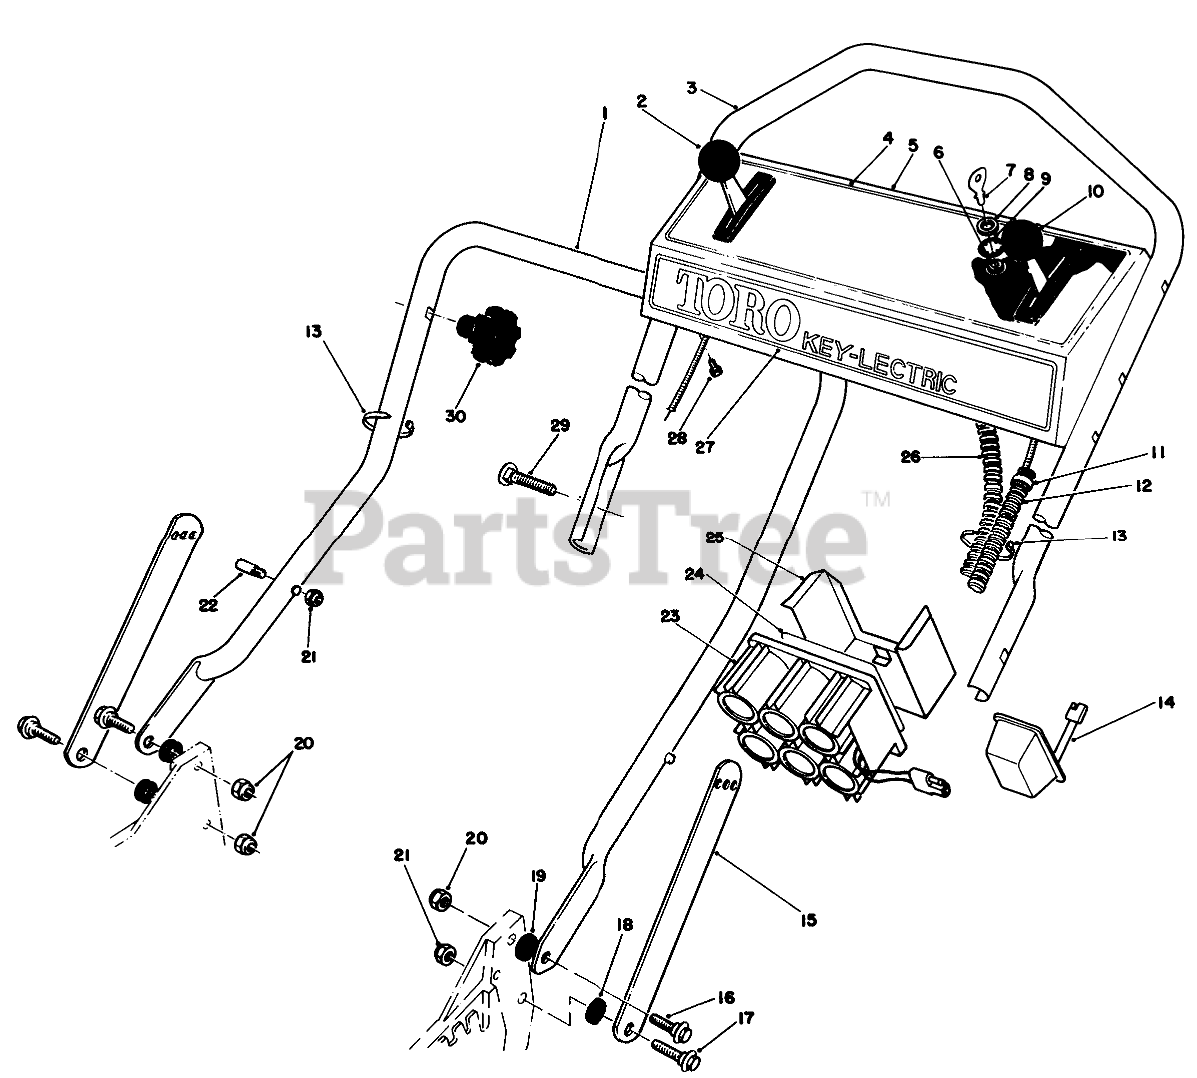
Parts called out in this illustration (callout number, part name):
1	LOWER HANDLE ASM
2	GROUND SPEED CONTROL
3	Handle-Upper
4	INST PANEL DECAL(INTL)
5	Panel-Control (Incl. Ref. #4)
6	Switch-Starter (Incl. Ref. #8-9)
7	Key
8	NUT-HH
9	WASHER-TOOTH, INTERNAL
10	THROTTLE CONT-SERVICE
11	FITTING-RING
12	CONTROL CABLE COVER
13	TIE-CABLE
14	Charger
15	Handle Latch
16	SCREW-SHOULDER
17	SCREW-SHOULDER
18	SPACER
19	SPACER
20	NUT-LOCK, NI
21	NUT-LOCK, NI
22	HANDLE PIN
23	BATTERY ASSEMBLY
24	Decal
25	Retainer-Battery
26	WIRE HARNESS
27	Decal-Toro Panel
28	SCREW-HWHTF
29	5/16-18 X 2 HNDLE SCREW
